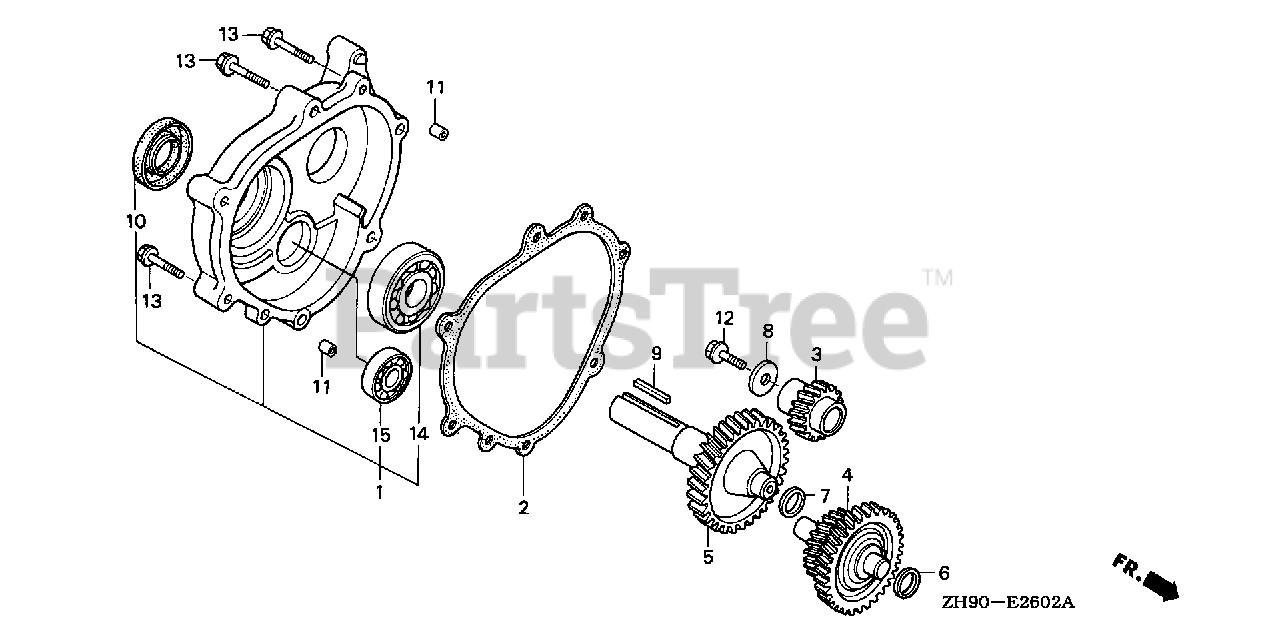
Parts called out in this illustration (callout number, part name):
1	COVER ASSY., REDUCTION CASE
2	GASKET, CHAIN CASE COVER
3	GEAR, PRIMARY DRIVE (17T)
4	COUNTERSHAFT (18T/40T)
5	SHAFT, P.T.O. (46T)
8	WASHER (8MM)
9	KEY (6.3X6.3X43)
10	OIL SEAL (30X46X8)
11	PIN, DOWEL (8X14)
12	BOLT, FLANGE (8X25)
13	BOLT, FLANGE (8X40)
14	BEARING, RADIAL BALL (6206)
15	BEARING, RADIAL BALL (6302)
